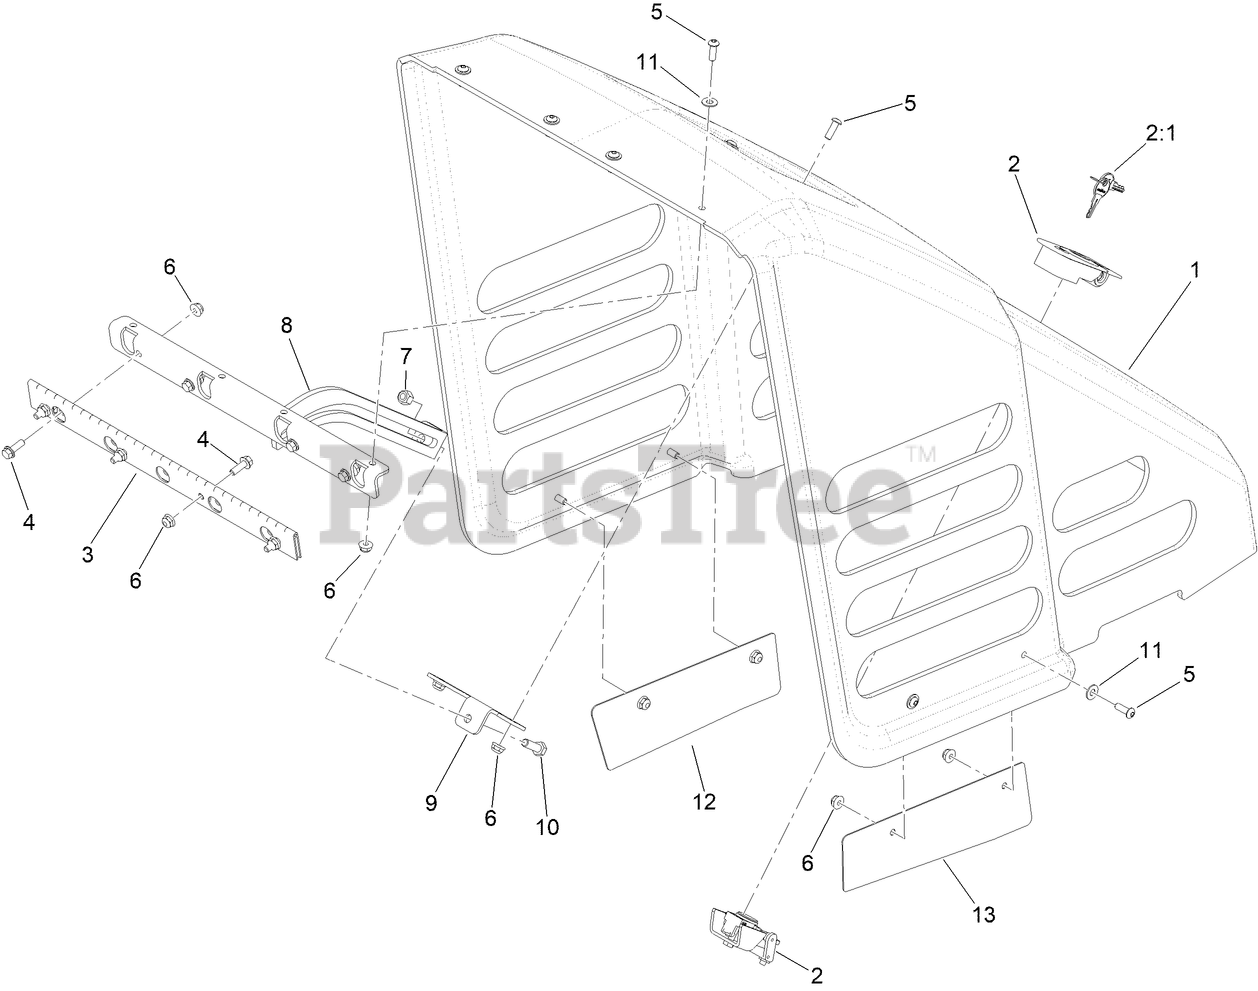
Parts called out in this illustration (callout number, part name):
2	LATCH-COMPRESSION, LOCKING
2:1	KEYS-LATCH
3	HINGE-HOOD
4	SCREW-HHF
5	SCREW-HSBH
6	NUT-HF
7	NUT-LOCK, NI
8	BRACKET-SLOT HOOD
9	BRACKET-ROD
10	SCREW-HH
11	WASHER-FLAT
12	HOOD-RETAINER,LH
13	HOOD-RETAINER,RH
